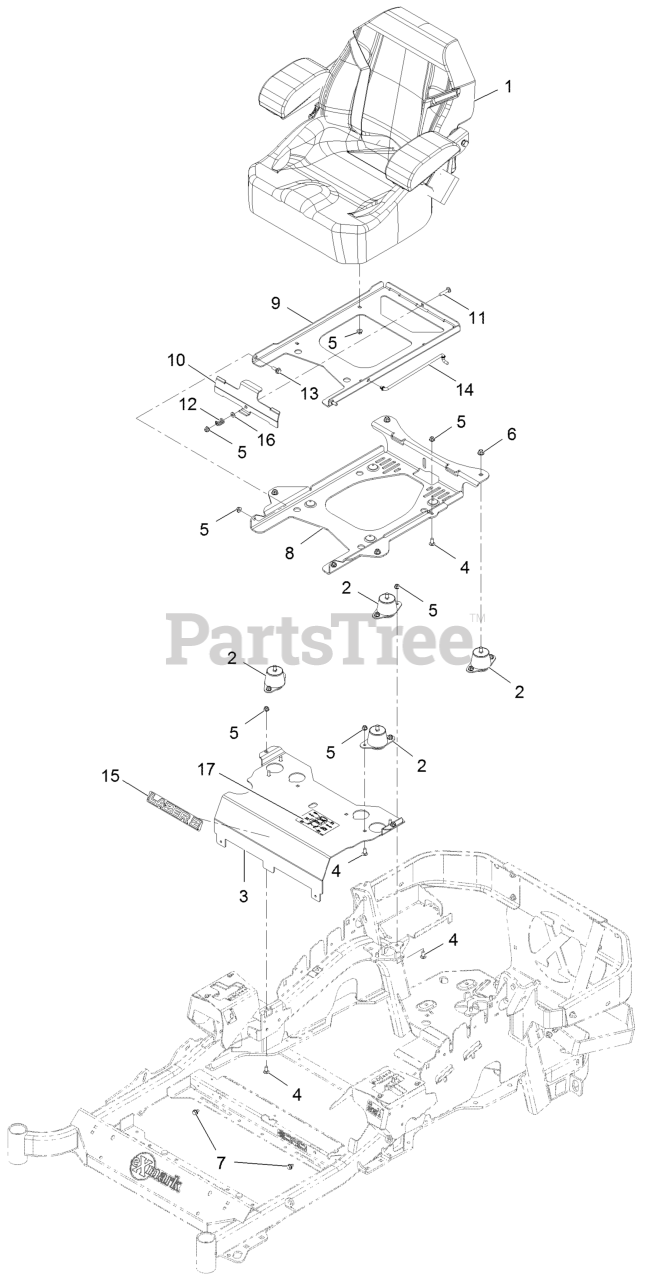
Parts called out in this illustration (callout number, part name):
1	SEAT-EXMARK STANDARD
2	ISOLATOR-SEAT
3	Panel-Front, Seat Mount
4	SCREW-CARR
5	NUT-HF, NI
6	NUT-HF, NI
8	PLATE-TILT, SEAT SUPPORT
9	PLATE-FRAME, SEAT
10	PLATE-LATCH, SEAT
11	BOLT-CARR
12	SPRING-COMPRESSION
13	SCREW-SHOULDER
14	ROD-PROP
15	DECAL, LAZER MODEL
16	WASHER-PLAIN
17	DECAL-SERVICE AID
